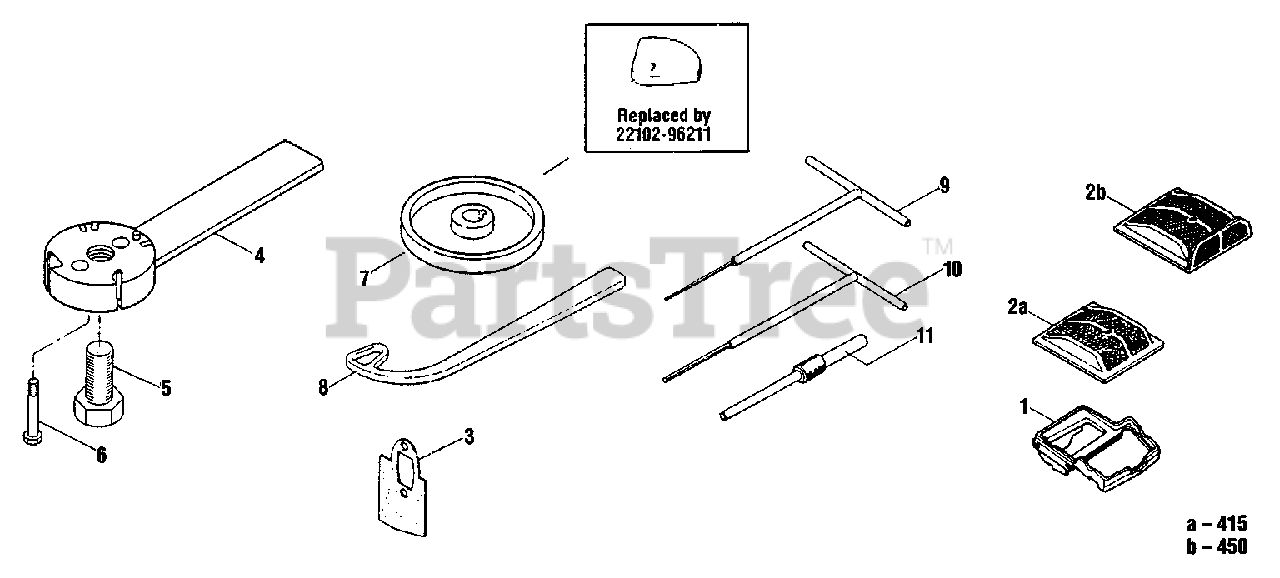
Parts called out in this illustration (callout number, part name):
1	DUCT, AIR
2A	FILTER, AIR - STAINLESS
2B	FILTER, AIR - STAINLESS
3	GASKET, EXHAUST
5	BOLT, CENTER
7	SET GAUGE
8	FLYWHEEL WRENCH
9	T-WRENCH - 3 MM
10	T-WRENCH - 4 MM
11	PIN, SET
